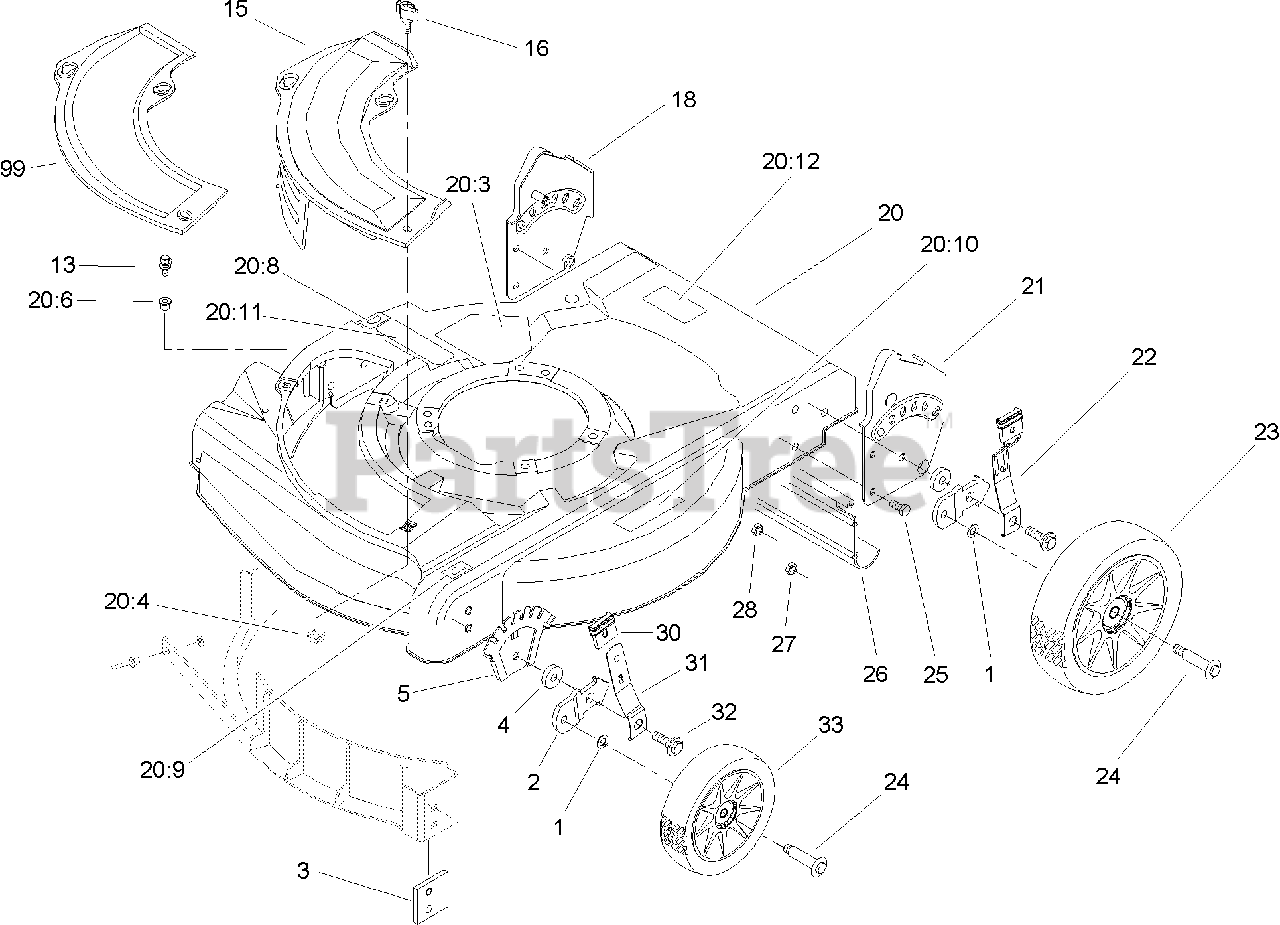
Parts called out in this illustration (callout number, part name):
2	BRACKET-HEIGHT ADJUSTMENT, WHEEL
3	PLATE-BAFFLE
4	WASHER-WHEEL
5	PLATE-HEIGHT, ADJUSTMENT
13	SCREW-SEMS
15	PLATE-MULCH
18	RH HANDLE BRACKET ASM
20:3	DECAL-DANGER
20:4	NUT-CAGE
20:6	NUT-CLIP
20:8	DECAL-HOC, LH
20:9	DECAL-HOC, RH
20:10	DECAL-WARNING
20:11	DECAL-WARNING
20:12	DECAL-MANUAL
21	LH HANDLE BRACKET ASM
22	REAR SPRING ARM ASM
23	WHEEL AND TIRE ASM
24	BOLT-SHOULDER
25	SCREW-HH
26	SHIELD-TRAILING
27	NUT-LOCK, NI
28	NUT-LOCK, NI
30	KNOB-LEVER, HEIGHT ADJUSTMENT
31	ARM-FRONT SPRING
32	BOLT-SHOULDER
33	WHEEL AND TIRE ASM
99	PLATE-OPENING, CHUTE
